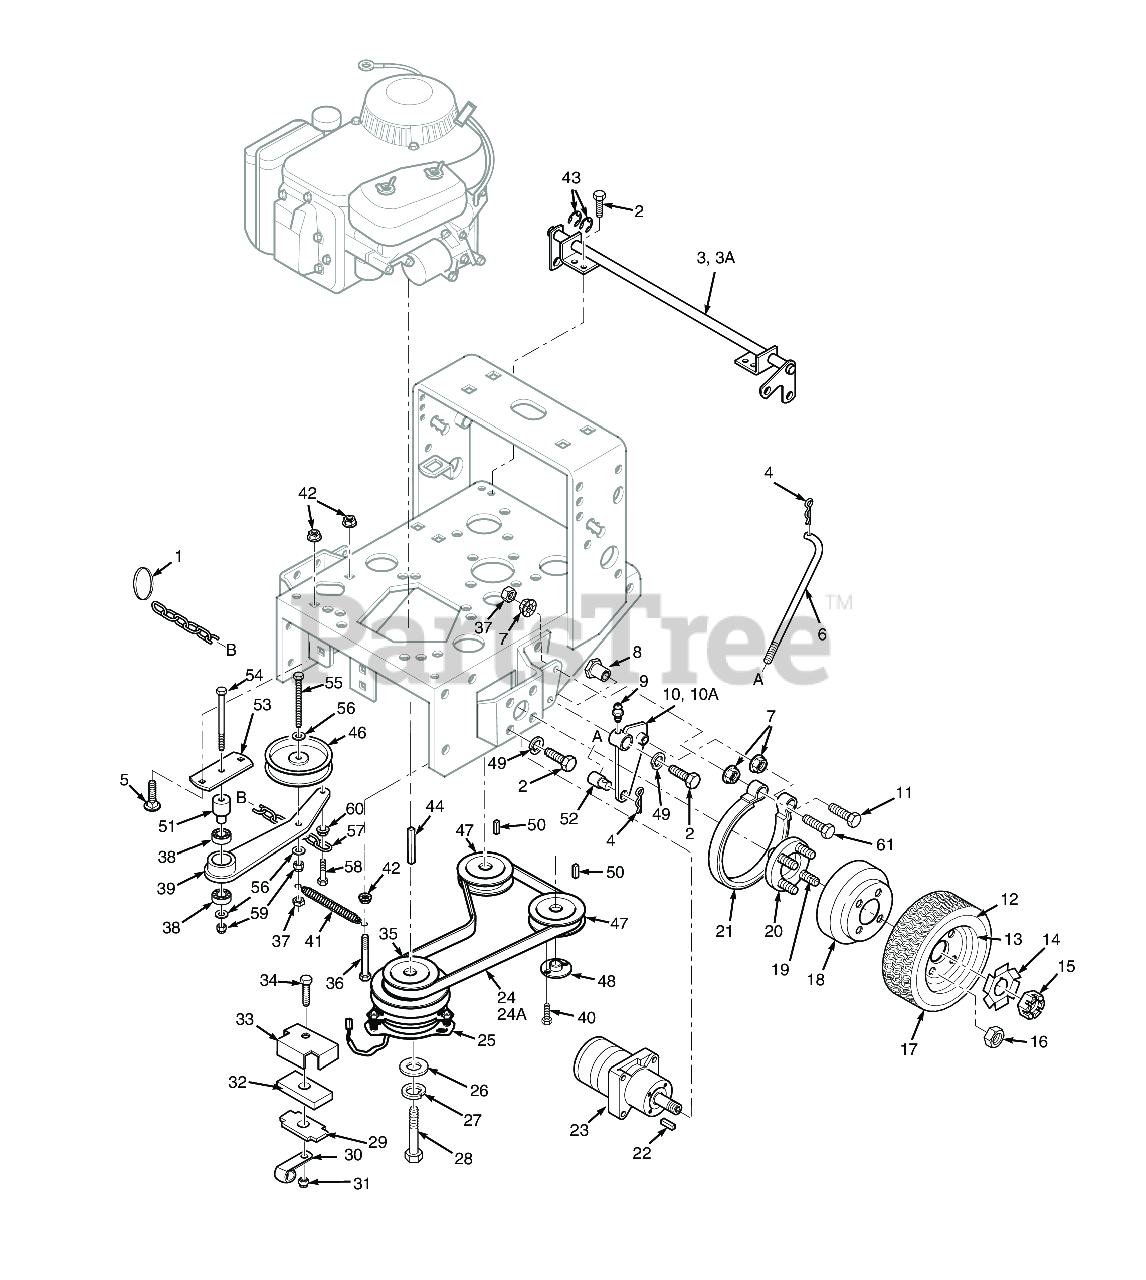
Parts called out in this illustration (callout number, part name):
1	Ring, Split
2	Bolt, Hex Head, 3/8-16 x 1 Gr. 5
3	Brake Shaft Assembly Weldment (16" Small Frame)
3A	Brake Shaft Assembly Weldment (20" Large Frame)
4	COTTER PIN, HAIR - 0.94 X 1.62
5	Bolt, 5/16-18 x .75 RHSN Carriage
6	Rod, Brake Lower
7	NUT, 3/8-16 SERRATED FLANGE HEX HEAD
8	B ushing, Brake
9	Greese Fitting, Straight 1/4 - 28
10	Brake Actuator Weldment, LH
10A	Brake Actuator Weldment, RH
11	Bolt, Hex Head 3/8-16 x 2-1/4" - 61"
12	Tire, 16 x 6.50, 4 ply
13	Rim Assy 481868 Rim Assy
14	Lock Washer, Wheel Motor
15	HEX CASTLE NUT, 3/4-28 UNEF
16	Wheel Nut, 1/2-20 x 13/16
17	Wheel Assy.,
18	Brake Drum
19	Bolt, Serr. Flange 1/2-20 x 4.563"
20	Wheel Hub Assembly
21	Brake Band Assembly
22	KEY, WOODRUFF #9, 3/16 X 3/4"
23	Wheel Motor
24	Belt, Pump Drive (16" Small Frame)
24A	Belt, Pump Drive (20" Large Frame)
25	Clutch, Electric (Ogura)
26	Flatwasher, 7/16-.469 x 1.75 x .25 (48, 52)
27	Lockwasher, 7/16� Spring
28	Bolt, Hex Head 7/16-20 x 2-3/4" w/ Patch
29	Plate, backing Clutch Pad
30	Clamp, Cable 1/2" I.D.
31	HEX NUT, ELASTIC STOP LOCK, 5/16-18
32	Rubber Pad, Clutch Stop
33	Backing Plate, Clutch Stop
34	Bolt, Hex Head 5/16-18 x 1-1/2" - Front
35	Pulley, Pump Drive Engine
36	Bolt, Hex Head, 5/16-18 x 2.75 Zinc.
37	Bolt, Hex Head 3/8-16 x 1" Ser. Flg.
38	BEARINGS, BALL, NEUTRAL RETURN
39	Idler Arm Weldment, Pump (incl. 38)
40	Bolt, Hex Head 1/4-20 x 1" Grade 8 Black
41	Spring, Transmission Idler
42	Nut, Serrated Flange 5/16-18 (Right Front Engine Mounting, Briggs and Kohler Only)
43	RETAINING RING, 3/4" EXTERNAL "E"
44	Key, 1/4 x 1/4 x 3-3/4"
45	Flatwasher, 3/8" Special (.391 x .938 x .105)
46	Pulley, Idler 4-1/2"
47	Pulley, 5.45 OD - Tapered Bore"
48	Hub, Tapered, 15mm Bore
49	Lockwasher, 3/8" Spring, Kawasaki FX / FS
50	KEY, 5 MM X 5 MM X 25 MM
51	Pivot, Idler Long - 52"
52	SWIVEL JOINT, SPEED CONTROL ROD
53	Pivot Weldment, Idler
54	Bolt, Hex Head 3/8-16 x 3" - 52"
55	Bolt, Hex Head 3/8-16 x 2-3/4" Full Thread
56	Flatwasher, 3/8 (.391 x .938 x .105 HD) Grade 8
57	Chain
58	SERR. FLG. HEX HEAD CAPSCREW, 5/16-18 X 3/4
59	HEX NUT, ELASTIC STOP LOCK, 3/8-16
60	NUT, 1/4-20 SERRATED FLANGE HEX HEAD
61	Bolt, Hex Head 3/8-16 x 2-1/4"
